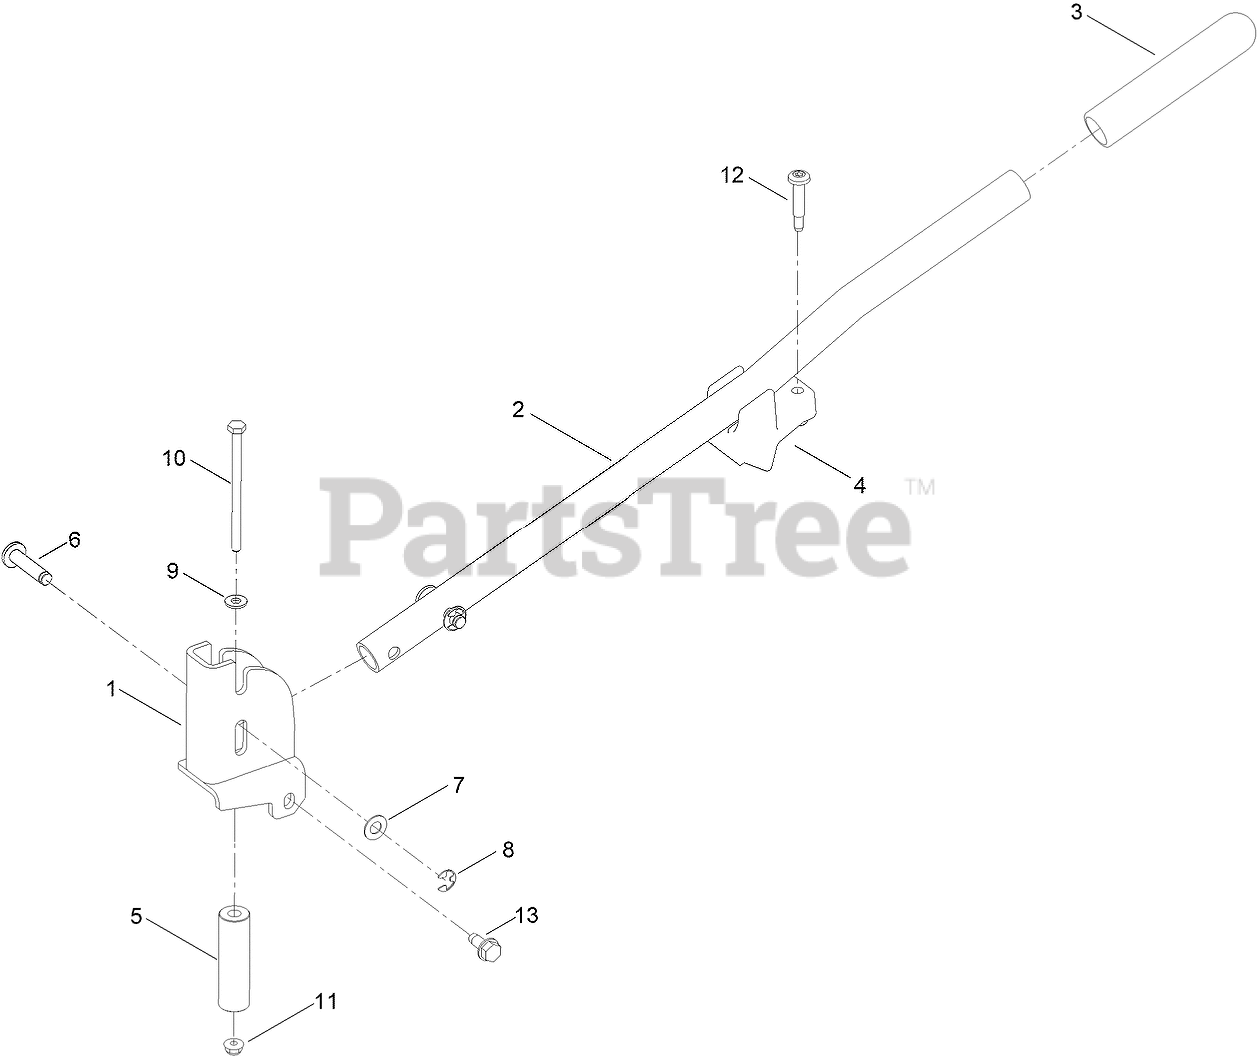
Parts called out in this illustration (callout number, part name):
1	WA-ASSIST BRACKET
2	TUBE-ASSIST
4	RETAINER-HANDLE
5	SPACER-SUPPORT
6	PIN-ASSIST HANDLE
7	WASHER-THRUST
8	E-RING
9	WASHER-FLAT
10	SCREW-HH
11	NUT-HF
12	SCREW-SHOULDER
13	SCREW-HWHTF
